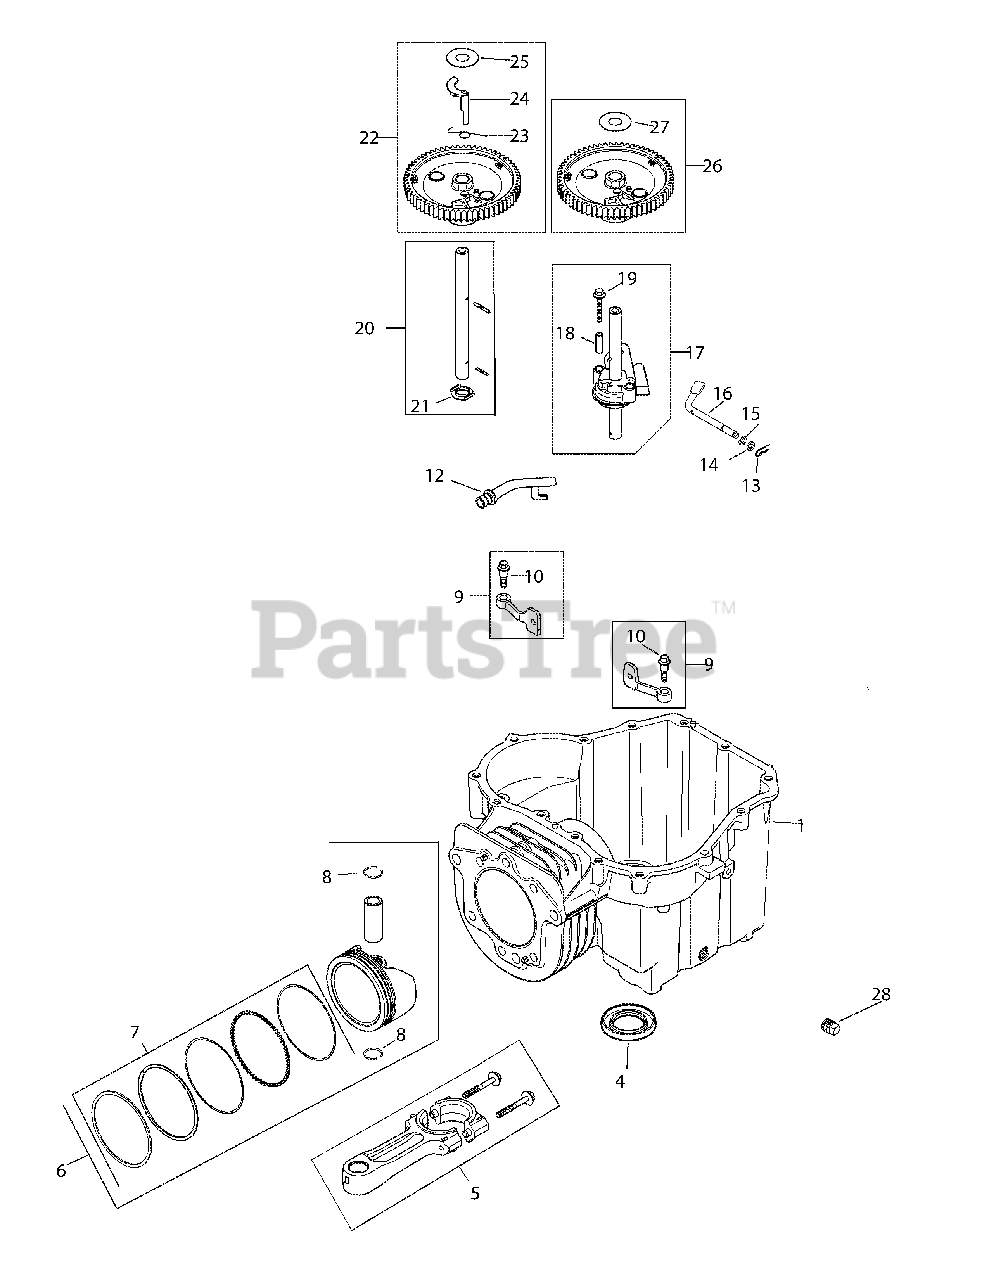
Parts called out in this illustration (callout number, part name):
1	Crankcase
4	Oil Seal
5	Connecting Assembly Rod
6	Piston w/ Ring Set, 94mm (Incl. 7, 8)
7	Ring Set (94mm)
8	Piston Pin Retainer
9	Cam Lever Ass. Kit (Incl. 10)
10	Shd. Thd. Frm. Screw, M6 X 1 X 26
12	Drainback Tube
13	Hitch Pin Clip
14	Flat Washer, 6 Mm
15	Flat Washer, 1/4
16	Governor Cross Shaft
17	Oil Pump Ass’y Kit (Incl. 11, 18, 19)
18	Oil Pump Screw Spacer
19	Oil Pump Screw
20	Cam Center Shaft Kit (Incl. 21)
21	Thrust Washer
22	Camshaft Ass’y Kit (Incl. 23-25)
24	Acr. Weight
25	Thrust -Acr. Washer
26	Camshaft Ass’y Kit (Incl. 27)
27	Thrust -Acr. Washer
28	Square Head Pipe Plug, 3/8
